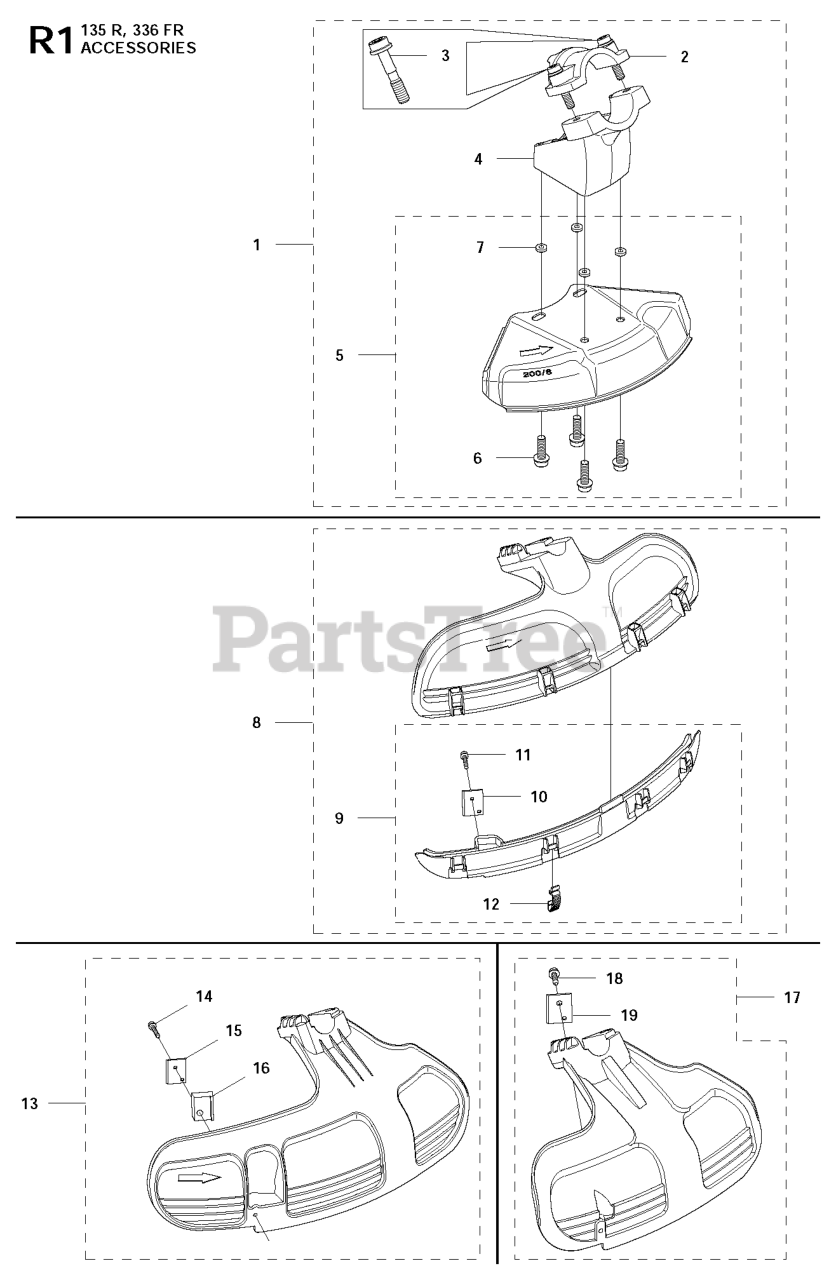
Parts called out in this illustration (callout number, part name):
2	CLAMP
3	SCREW IHSCFMO
4	ADAPTER
5	BLADE GUARD
7	LOCKING NUT
8	COMBI PROTECTOR
9	SPLASH GUARD
16	DISTANSBLOCK
17	TRIMMER GUARD ASSY
